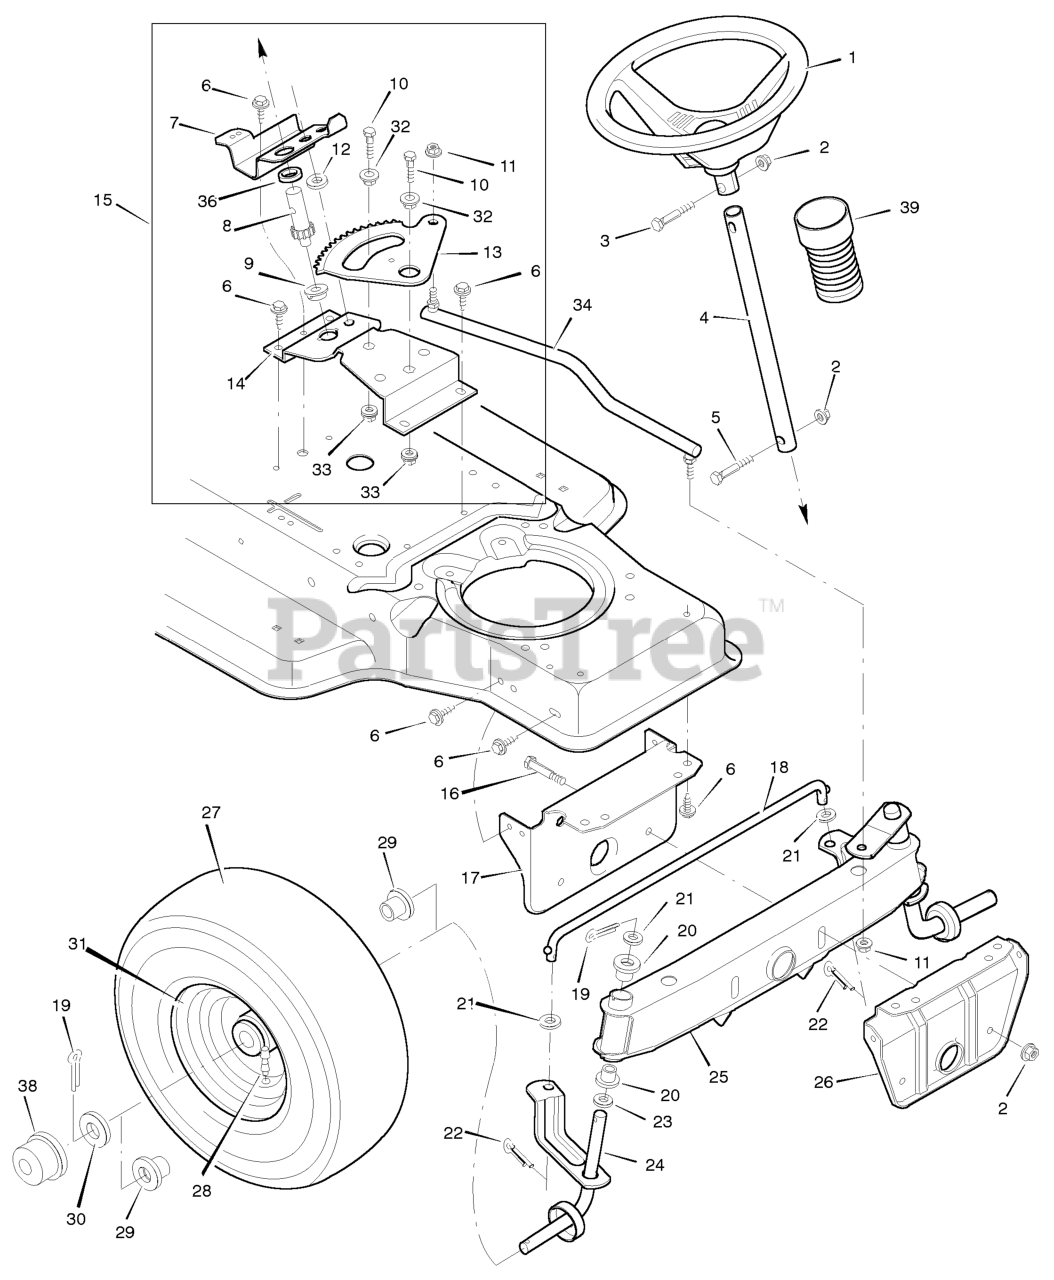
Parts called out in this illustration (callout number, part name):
1	Wheel, Steering
2	Nut, Hex
3	Bolt, Hex
4	Post, Steering
5	Bolt, Hex
7	Bracket, Sector
8	Gear, Pinion
9	Bearing
10	CAPSCREW, Hex Head, 5/16-18 x 1
11	Locknut, Flange
13	Gear, Sector
14	Bracket, Sector
15	Kit, Steering Gear
16	Bolt, Hex
17	Support, Rear Axle
18	Rod, Tie
19	Pin, Cotter
20	Bearing
22	Pin, Cotter
24	Spindle Assembly, Right
25	Spindle Assembly, Axle & Left
26	Support, Front Axle
27	Tire *
28	Stem, Valve
29	Bearing, Wheel
31	Wheel & Tire Assembly
32	Bearing
33	Locknut, Flange
34	Link, Drag
36	Spacer, Pinion Gear
38	Hub Cap
39	Bellows
